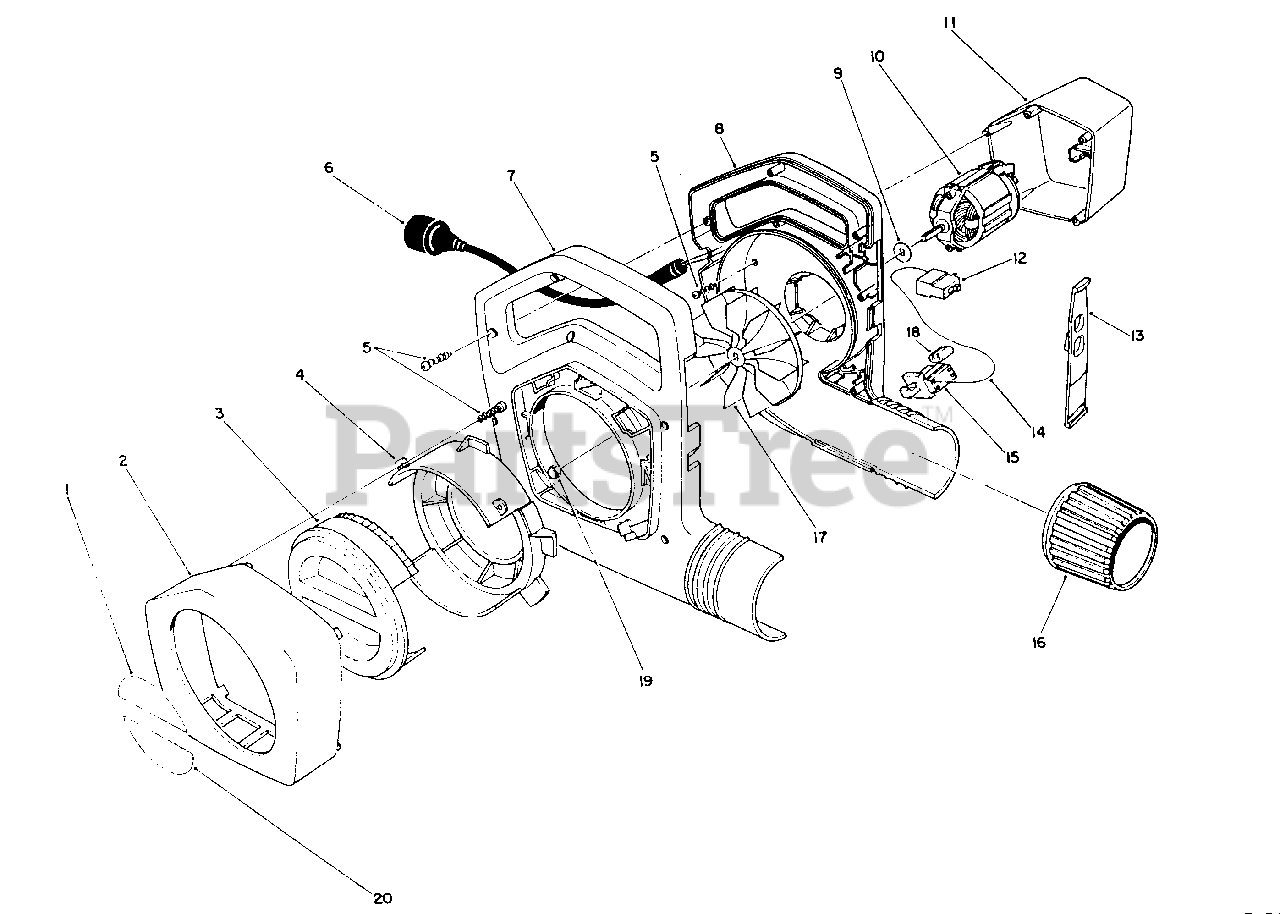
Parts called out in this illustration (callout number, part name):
1	Decal-Choke, Upper
2	Ring-Trim
3	Adjuster-Choke
4	Ring-Tab
5	Screw
6	Cord-Power Supply
7	Housing Assembly-R.H.
8	Housing-L.H.
9	Washer-Impeller
11	Cover-Motor
12	Switch-On/Off
13	Cam-Switch, On/Off
14	Wire-Internal
15	Switch-Interlock
16	Collar-Output
17	Impeller
18	Plug-Dust
20	Decal-Choke, Lower
